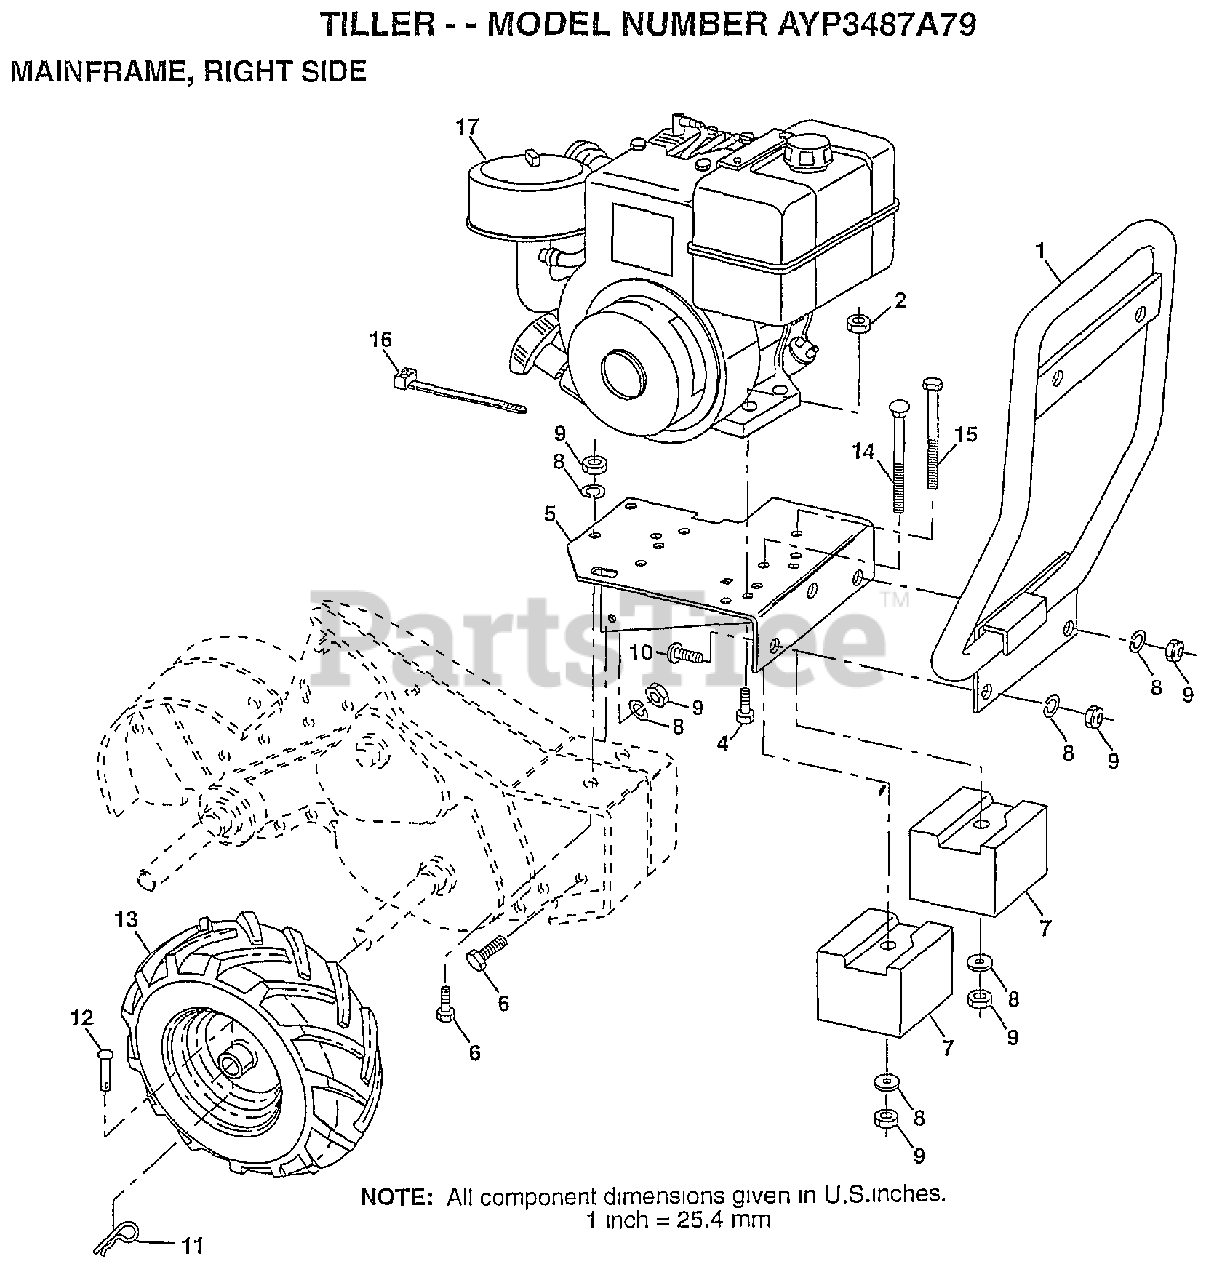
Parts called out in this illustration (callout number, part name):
1	BUMPER.ASM
4	BOLT
5	"ASM. ENGINE, BASE"
6	BOLT
7	COUNTERWEIGHT CRT
8	LOCKWASHER
9	NUT.HEX.3/8-16UNC
11	SPRING.RETAINER
12	RIVET.PAN HD.1.75
13	TIRE TI
14	BOLT CRT
15	BOLT.3/8-16X4.5
16	TIE CABLE CRT
